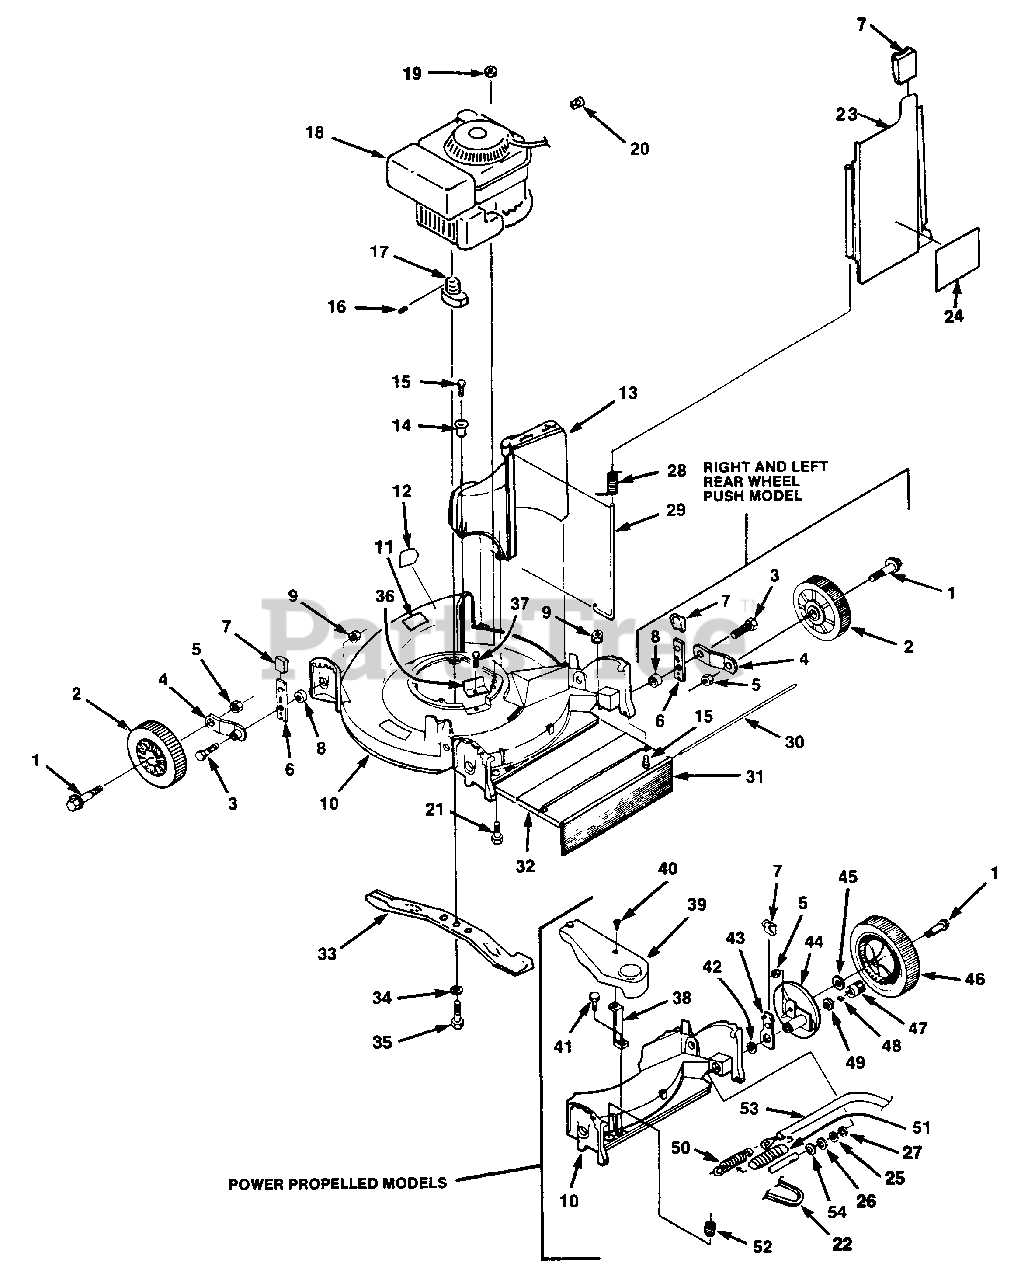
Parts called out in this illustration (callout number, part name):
1	BOLT- Axle (3/8 x 24)
2	WHEEL & TIRE
3	BOLT- Hex hd. (5/16-18)
4	ARM- Wheel hgt. adj.
5	NUT- Hex (3/8-24)
6	SPRING- Index
7	KNOB- Indexing spring
8	SPACER- Indexing spring
9	NUT- Flange (5/16-18)
10	DECK- 21"
11	DECAL- Gasohol
12	DECAL- Warning
13	CHUTE- Discharge
14	EYELET- Simpson
15	SCREW- Hex hd. (1/4-20 x 3/4")
16	KEY- 5/8 x 5/32"
17	ADAPTER- Blade
18	ENGINE- 4.0 HP, 2 Cycle
19	NUT- Hex lock (5/16-18)
20	STOP- Rope
21	BOLT- Hex (5/16-18 x 1")
22	BELT- Drive
23	DOOR- Chute
24	DECAL- Door
25	WASHER- Shim
26	WASHER
27	WASHER- Flat
28	SPRING- Door
29	PIN- Hinge
30	ROD- Drap flap
31	FLAP- Drag
32	COVER- Rear
33	BLADE- 21"
34	WASHER- Lock (7/16")
35	BOLT- Shoulder
36	COVER- Belt opening
37	SCREW- (Hex hd. 1/4-20 x 1/2")
38	SUPPORT
39	COVER- Drive
40	SCREW- (Rd. Hd. 1/4-20 x 3/4")
41	SCREW- (Hex hd. 10-16 x 1/2")
42	SPACER- Hgt. Adj.
43	SPRING- Index
44	DRIVE WHEEL SUPPORT
45	WASHER- Flat
46	WHEEL & TIRE (drive)
47	PINION- R.H.
48	PAWL- Pinion
49	WASHER- Flat
50	SPRING- Traction lever
51	COVER- Spring
52	SPRING- Compression
53	CABLE- Traction
54	RING- Eaton
